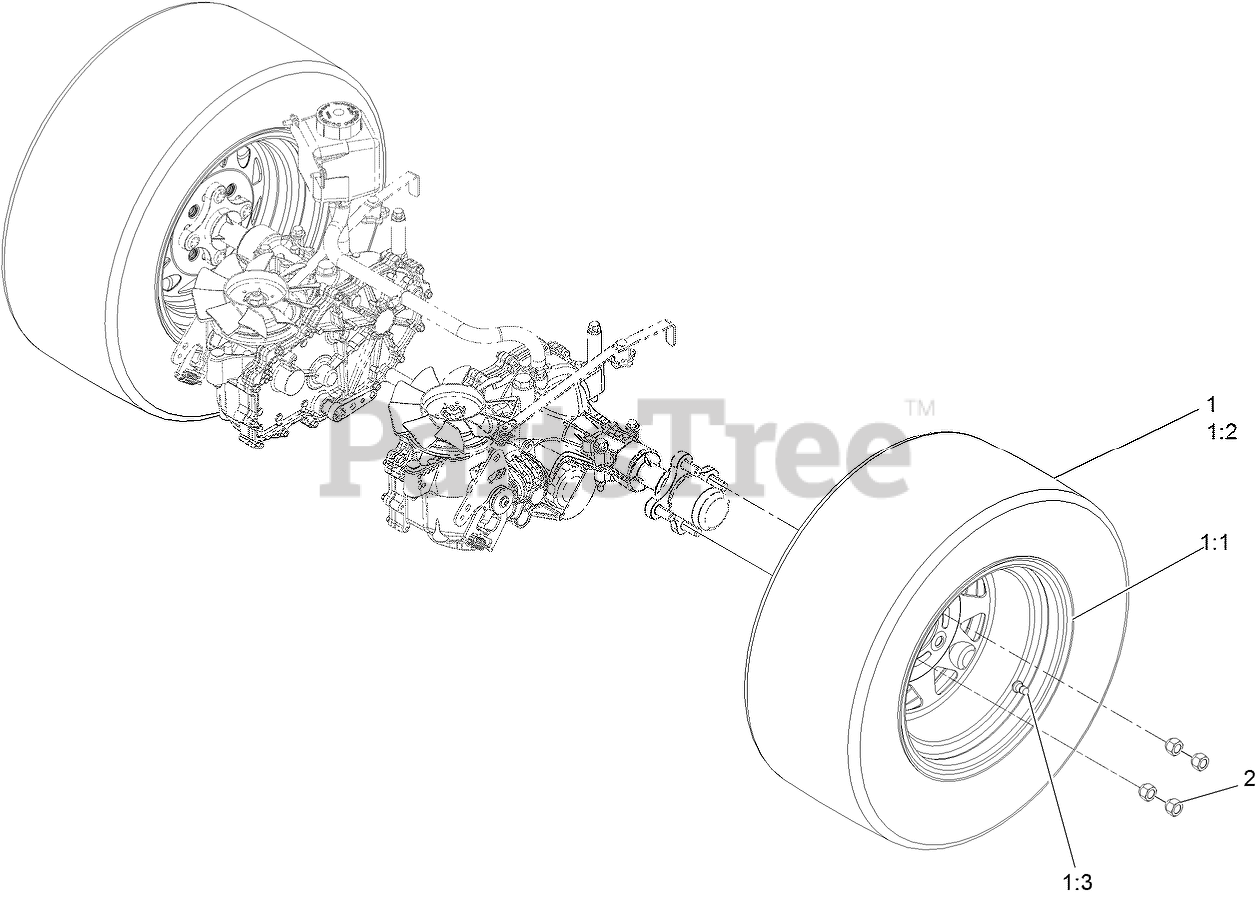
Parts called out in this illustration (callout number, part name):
1	WHEEL AND TIRE ASM
1:3	VALVE
2	NUT-LUG
